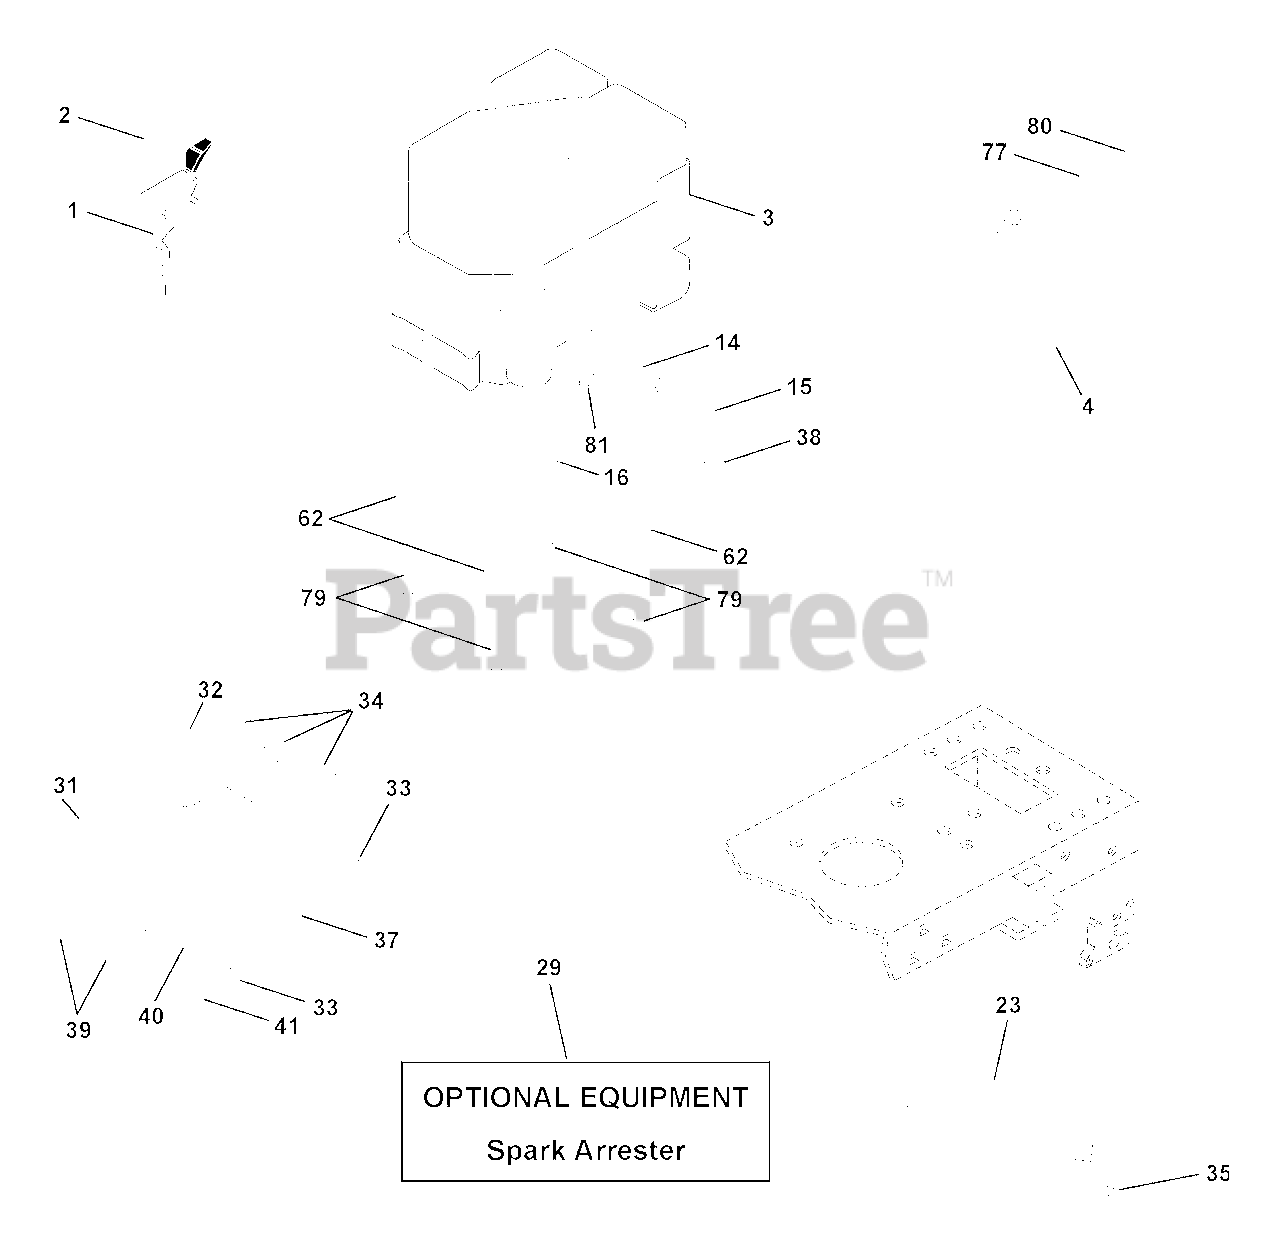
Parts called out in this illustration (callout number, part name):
1	Control Th/ch 27. LH. Flag Dom.
2	Screw Hex Thd Cut 1/4-20x5/8 T
3	Engine Kohler
4	Muffler LT Kohler 12.5/15HP
14	Nipple Pipe 3/8 Npt X 3-1/2
15	Elbow Std 90 Degree 3/8-18 Npt
16	Washer Lock Ext Tooth 5/16
23	Shield Heat
29	Kit Spark Arrestor (Flat Scrn)
31	Tank Fuel 3.5 STLT W/O Sensor
32	Cap Asm Fuel W/sym Vented
33	Clamp Hose Black
34	Pad Spacer
35	Screw
37	Line Fuel 7.5
38	Plug Oil Drain
39	Pad Idler 1.75 x .75 x .06
40	Bushing
41	Stem Tank Fuel
62	Washer Lock Hvy Hlcl Spr 5/16
77	Washer 5/16 x 3/4 x 16 Ga.
79	Bolt Hex
80	Bolt Hex Hd. 5/16-18unc x 1/2
81	Nut Flange 1/4-20 Starter Nut
